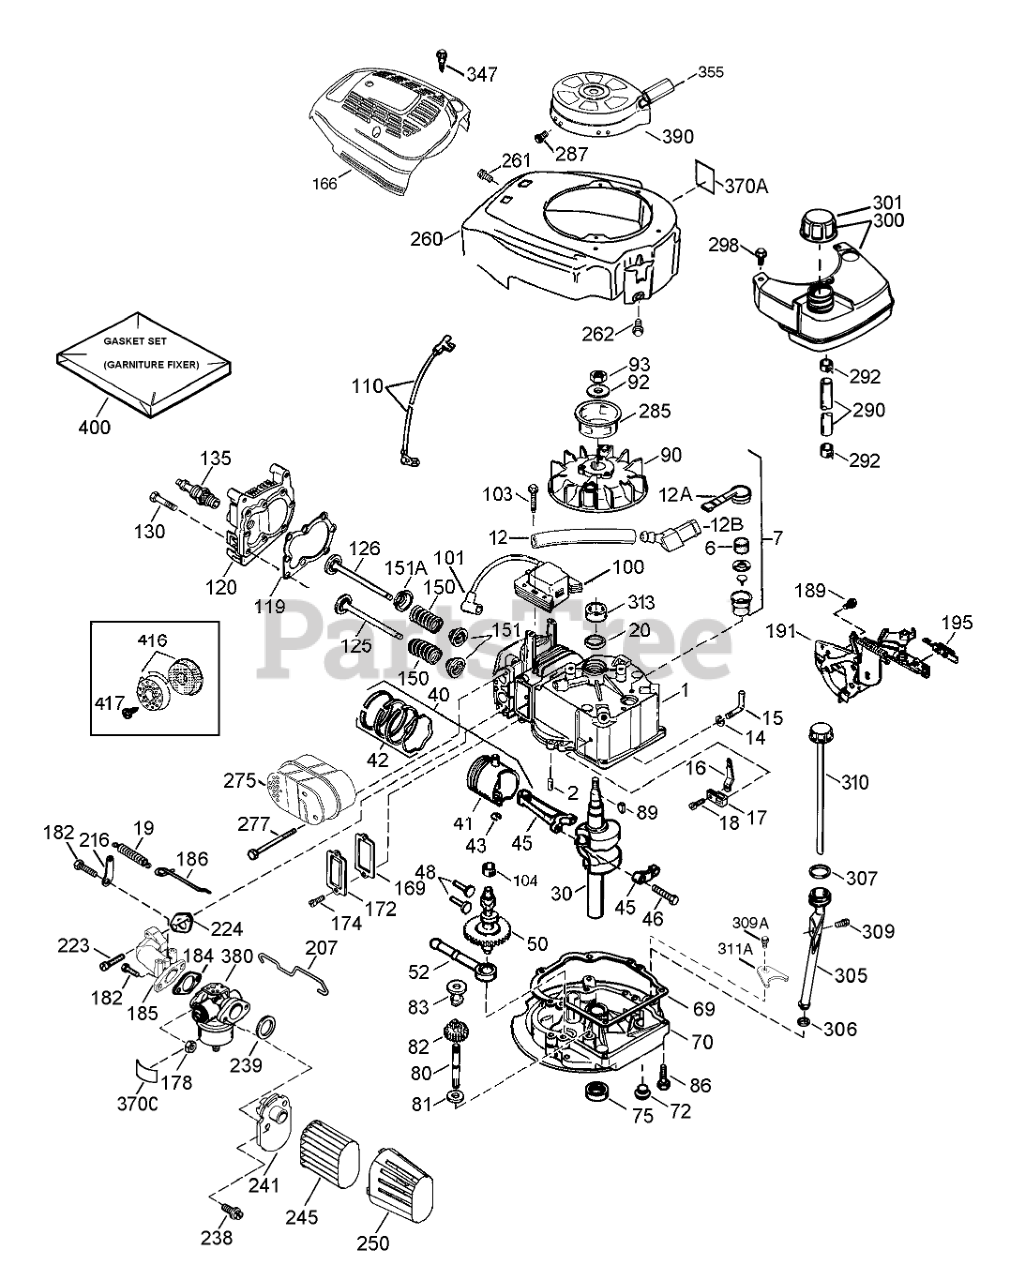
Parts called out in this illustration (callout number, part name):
1	Cylinder (Incl. 2, 20 &150)
2	Pin-Dowel
6	Element-Breather
7	Breather Ass-y. (Incl. 6 & 12A)
12	Tube-Breather
12A	Breather Cover & Tube (Incl. 12B)
12B	Elbow-Tube, Breather
14	Washer-Flat
15	Governor Rod (Incl. 14)
16	Lever-Governor
17	Clamp-Lever, Governor
18	Screw (T-15, 8-32 x 19/64)
19	Spring-Extension
20	Seal-Oil
30	Crankshaft
40	Piston, Pin and Ring Set (Std.)
41	Piston & Pin Ass-y. (Std.)(Incl. 43)
42	Ring Set (STD)
43	Ring-Retaining, Piston Pin
45	Connecting Rod Ass-y. (Incl. 46)
46	Bolt-Rod, Connecting
48	Lifter-Valve
50	Camshaft (Exhaust MCR)(Inc. 104)
52	Oil Pump ASM
69	Gasket-Flange, Mounting
70	Mounting Flange (Incl. 72-83,306,309A & 311A)
72	Plug-Drain, Oil
75	Seal-Oil
80	Shaft-Governor
81	Washer-Flat
82	Governor Gear Ass-y. (Incl. 81)
83	Spool-Governor
86	Screw (1/4-20 x 1-1/4)
89	Key-Flywheel
90	Flywheel
92	Washer-Belleville
93	Nut-Flywheel
100	Ignition-State, Solid
101	Cover-Spark Plug
103	Screw (T-15, 10-24 x 15/16)
104	Bushing-Cam
110	Wire-Ground
119	Gasket-Cylinder Head
120	Head-Cylinder
125	Exhaust Valve (1/32" OS)(Incl. 151)
125	Exhaust Valve (Std.)(Incl. 151)
126	Intake Valve (Std.)(Incl. 151 & 151A)
130	Screw (5/16-18x1-1/2)
135	Spark Plug-Resistor (R J19 L M)
150	Spring-Valve
151	Cap-Valve, Spring
151A	Seal-Valve, Intake
166	Shroud-Engine
169	Gasket-Cover, Valve
172	Cover-Valve
174	Screw (10-24 x 9/16)
178	Nut and Lock Washer (1/4-28)
182	Screw (1/4-28 x 7/8)
184	Gasket
185	Pipe-Intake
186	Link-Governor
189	Screw (1/4-20 x 3/8)
191	S.E. Brake Bracket (Incl. 195)
195	Terminal
207	Link-Throttle
216	Lever-Adjusting, R P M
223	Screw (1/4-20 x 1)
224	Gasket-Pipe, Intake
238	Screw (10-32 x 49/64)
239	Gasket-Cleaner, Air
241	Collar-Cleaner, Air
245	Filter-Cleaner, Air (Paper)
250	Cover-Cleaner, Air
260	Housing-Blower
261	Screw (10-24 x 9/16)
262	Screw (1/4-20 x 1/2)
275	Muffler
277	Screw (1/4-20 x 2-9/32)
285	Cup-Starter
287	Screw (8-32 x 21/64)
290	Line-Fuel (8.62)
292	Clamp-Line, Fuel
300	Fuel Tank (Incl. 292 & 301)
301	Cap-Fuel
305	Tube-Fill, Oil
306	O-Ring
307	O-Ring
309	Screw (10-32 x 1/2)
309A	Screw (10-24 x 3/4)
310	Dipstick
311A	Bracket-Holddown
313	Spacer
347	Screw (10-32 x 27/32)
370	Decal-Warning
370A	Decal-Lubrication
370C	Decal-Primer
380	Carburetor (Incl. 184)
390	Rewind Starter ASM
400	Gasket Set (Incl. Items Marked in Notes)
416	Spark Arrestor Kit
